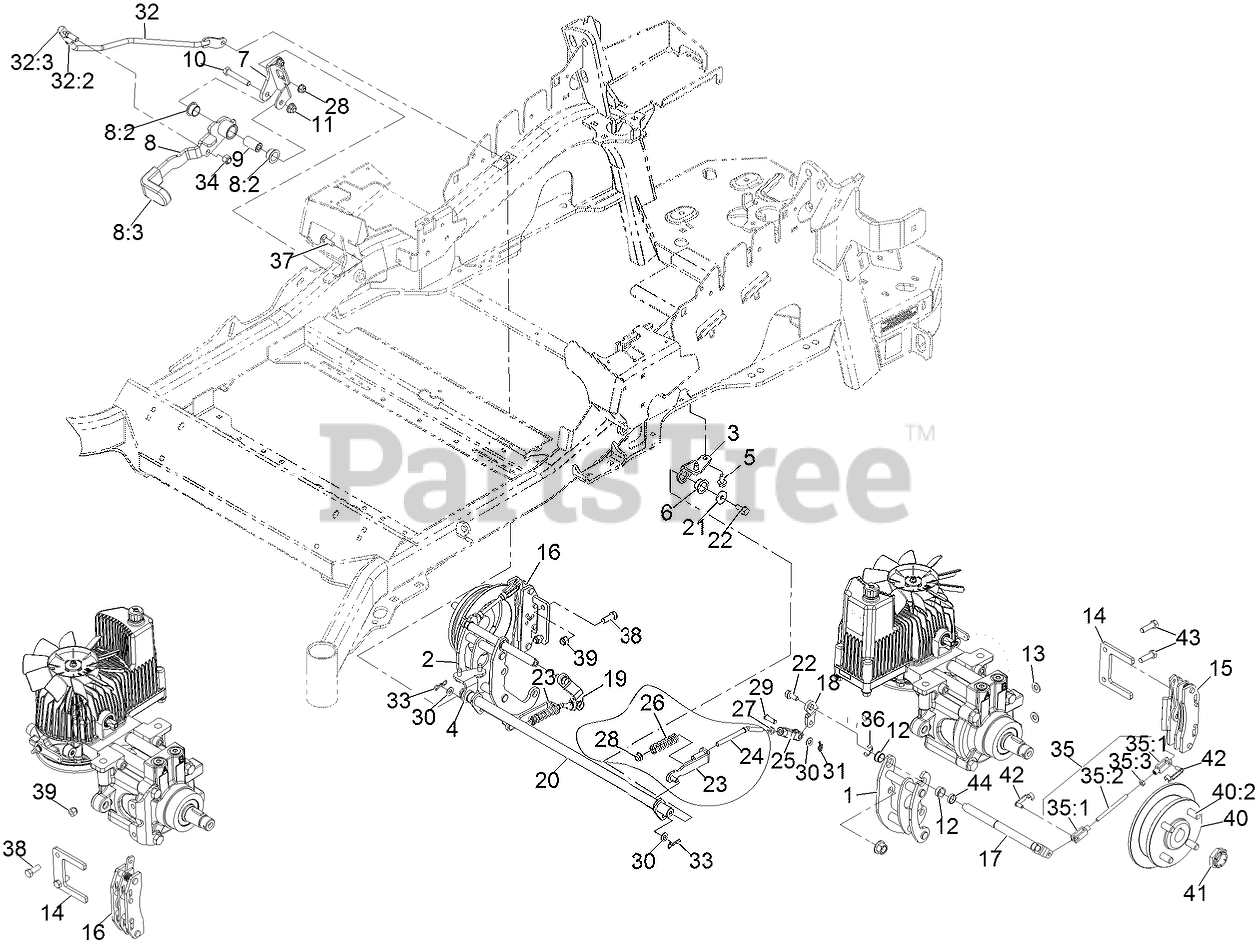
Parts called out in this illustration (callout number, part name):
1	MOUNT-BELLCRANK, LH
2	MOUNT-BELLCRANK, RH
3	MOUNT-PIVOT, LH
4	MOUNT-PIVOT, RH
5	Screw-HWH 5/16-18 X 3/4 Tf
6	BUSHING-FLANGE
7	BRACKET-MOUNT
8	BRAKE LEVER ASM W/ GRIP
8:2	BUSHING-FLANGE
8:3	GRIP-LEVER
9	HANDLE-PIVOT, BRAKE
10	SCREW-HH
11	NUT-HF, NI
12	BUSHING
13	WASHER-FLAT
14	PLATE-MOUNT, BRAKE
15	CALIPER-BRAKE
16	CALIPER-BRAKE, RH
17	BELLCRANK
18	ARM-INNER, LH
19	ARM-INNER, RH
20	SHAFT-CROSS
21	WASHER-FLAT
22	SCREW-HHF
23	BRACKET-L
24	LINKAGE-MID
25	YOKE-OFFSET
26	SPRING-COMPRESSION
27	NUT-JAM
28	NUT-HF, NI
29	PIN-CLEVIS
30	WASHER-PLAIN
31	PIN-COTTER, LOCKING
32	FRONT LINKAGE ASM
32:2	NUT-HJ
32:3	END-TIE ROD, RH
33	PIN-COTTER, LOCKING
34	NUT-LOCK
35	REAR LINKAGE ASM
35:3	NUT-JAM
37	BOLT-CARR
38	SCREW-HH
39	NUT-LOCK, NI
40	WHEEL HUB ASM
40:2	STUD-WHEEL
41	LOCKNUT
42	PIN-CLEVIS, SPRING
43	SCREW-LOCK, PATCH
